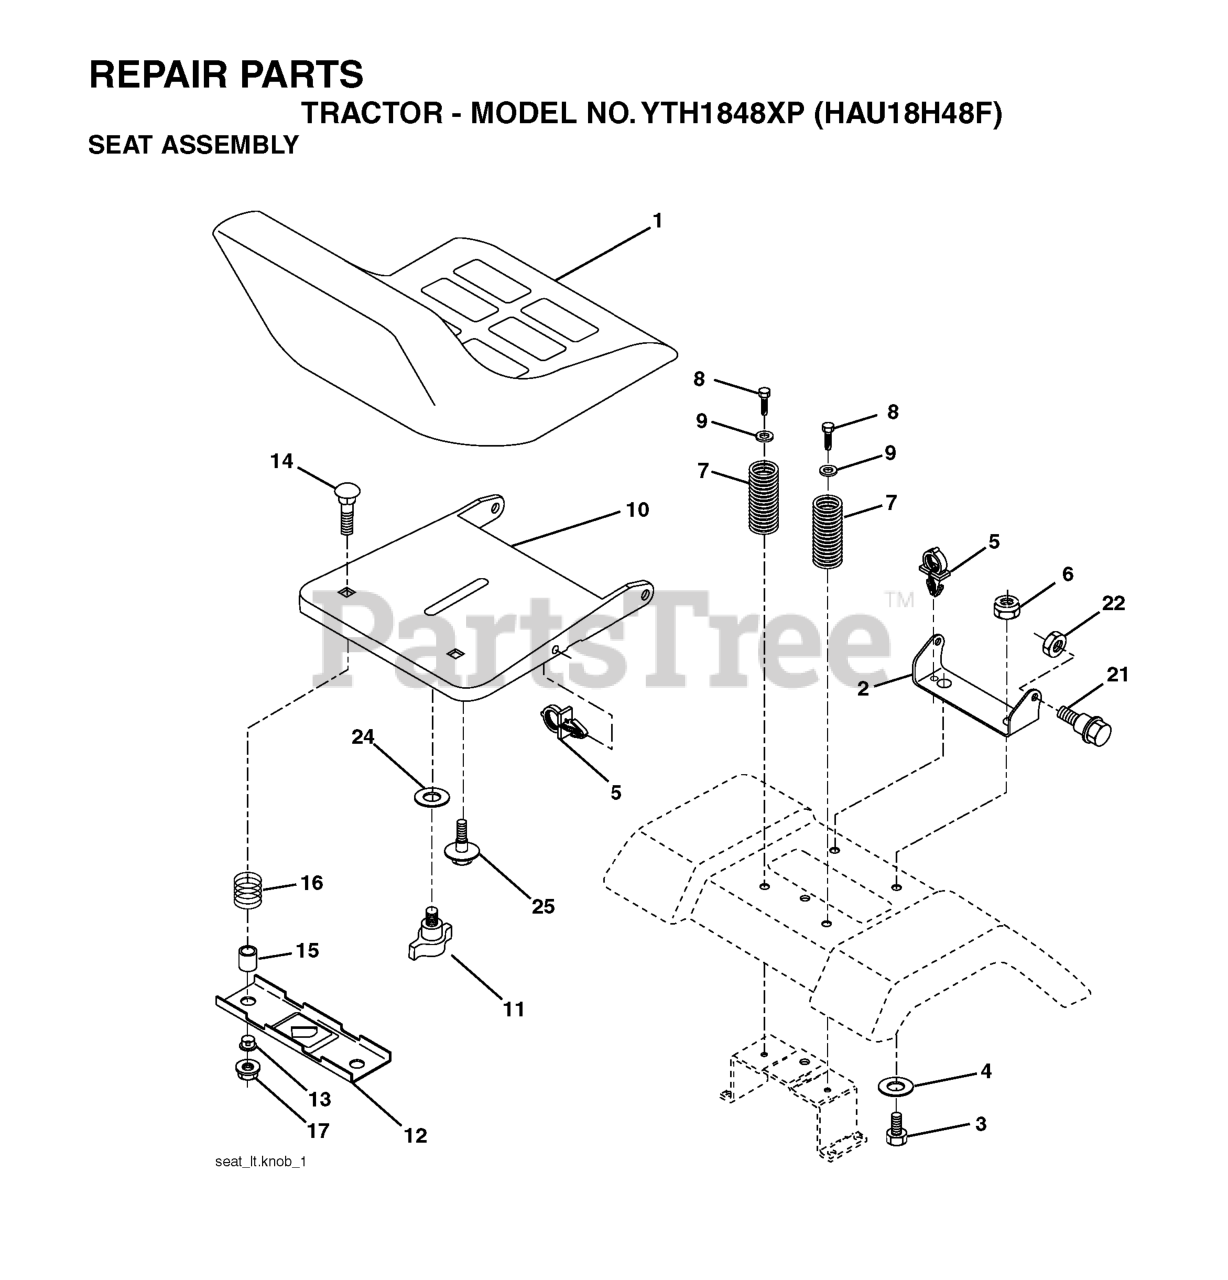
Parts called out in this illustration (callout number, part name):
1	SEAT, GRAY
2	SEAT PIVOT BRKT
3	BOLT, HEX 3/8-16X1
6	NUT
7	SPRING COMPRESSION
8	SCREW 3/8-16X1
9	WASHER
10	PAN SEAT
11	KNOB.SEAT.ADJ.WINGNUT
12	BRKT SWITCH
14	BOLT.ROUND.HEAD.SQUARE.NECK
15	SPACER SPLIT
16	SPRING COMPRESSED
17	NUT T
21	BOLT.SHOULDER.5/16-18
22	NUT.71038.31-18.HEX.NYLOCK
25	BOLT,SHOULD
